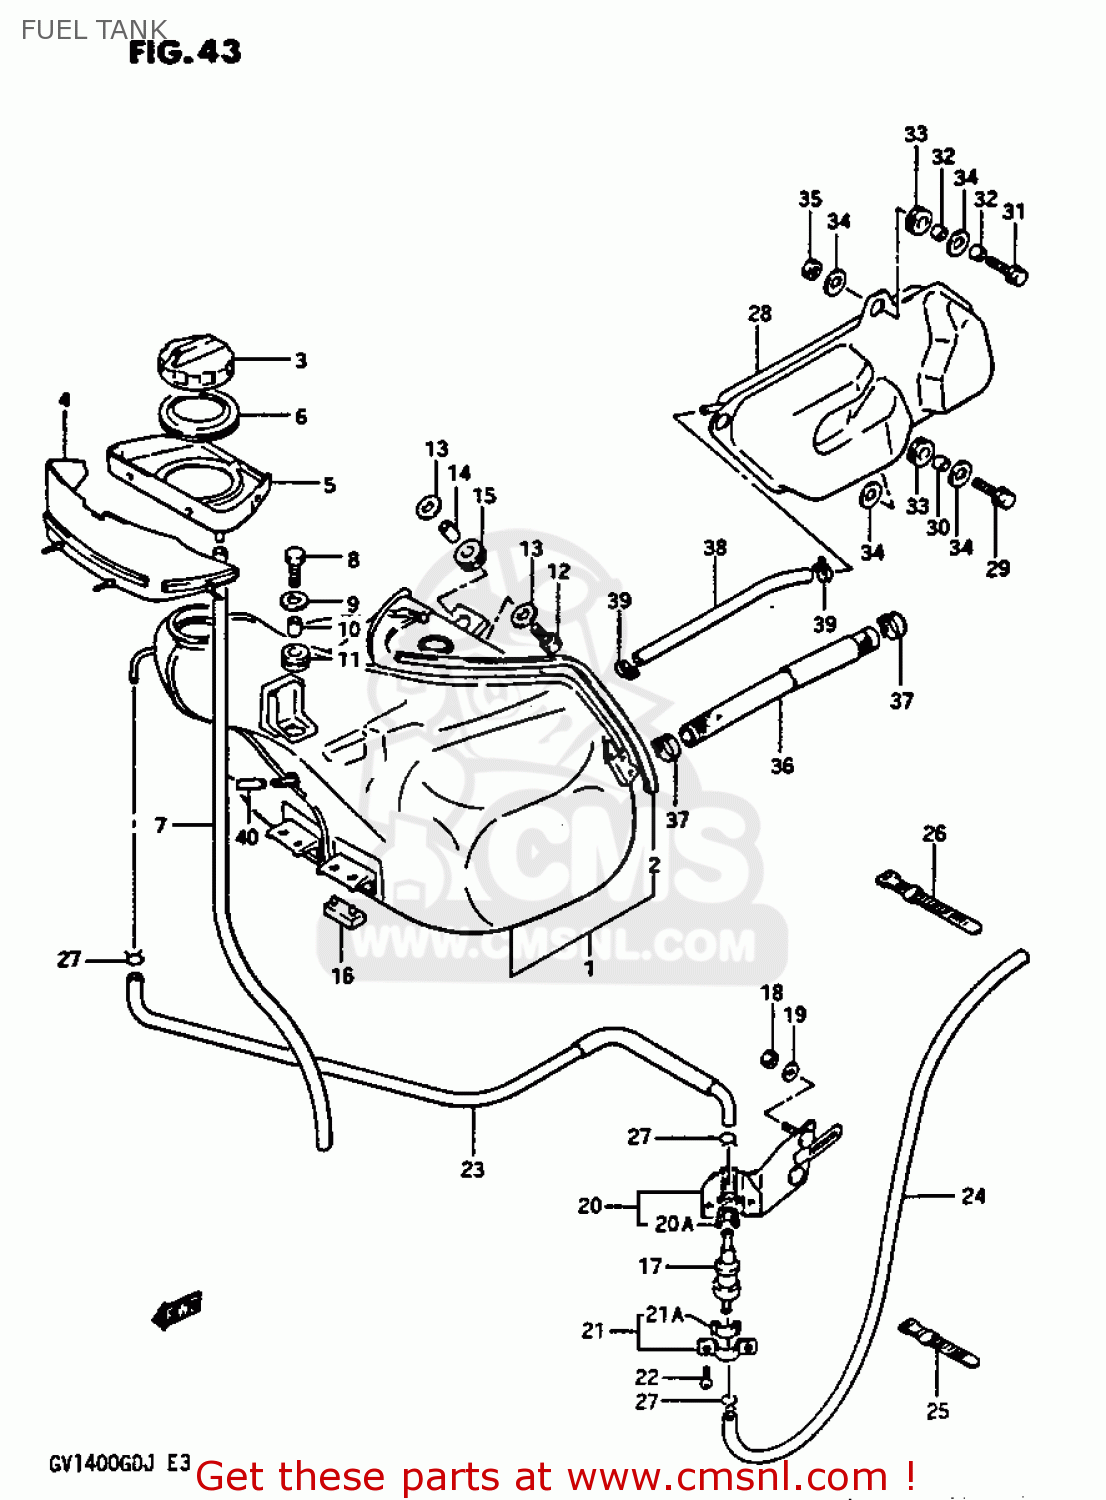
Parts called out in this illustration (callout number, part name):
1	TANK ASSEMBLY,FUEL
2	MOLDING, NO.2
3	CAP ASSEMBLY,FUEL TANK
4	COVER,FUEL INLET TRAY
5	TRAY, FUEL INLET
6	JOINT,FUEL INLET,TRAY
7	HOSE
8	BOLT,M6X1X20
9	WASHER(6.5X20X1.6)
10	SPACER(6.1X9X7.5)
11	CUSHION
12	BOLT
13	WASHER (8.5X29X1.6)
14	SPACER (8.6X13.8X8)
15	CUSHION
16	CUSHION
17	VALVE,FUEL TANK BREATHER
18	NUT 6MM
19	WASHER(6.5X18X1)
20	PLATE,TANK BREATHER VALVE
20A	CUSHION
21	PLATE,FUEL TANK BREATHER NO.2
21A	CUSHION
22	SCREW
23	HOSE
24	HOSE
25	CLAMP(L:125)
26	CLAMP(L:187)
27	(CA) CLIP
28	SUB TANK,FUEL
29	BOLT
30	SPACER (8.8X12X11)
31	BOLT 8X40
32	SPACER(8.4X12X12)
33	CUSHION
34	WASHER
35	NUT
36	HOSE
37	CLAMP
38	HOSE
39	CLAMP
40	HOSE
